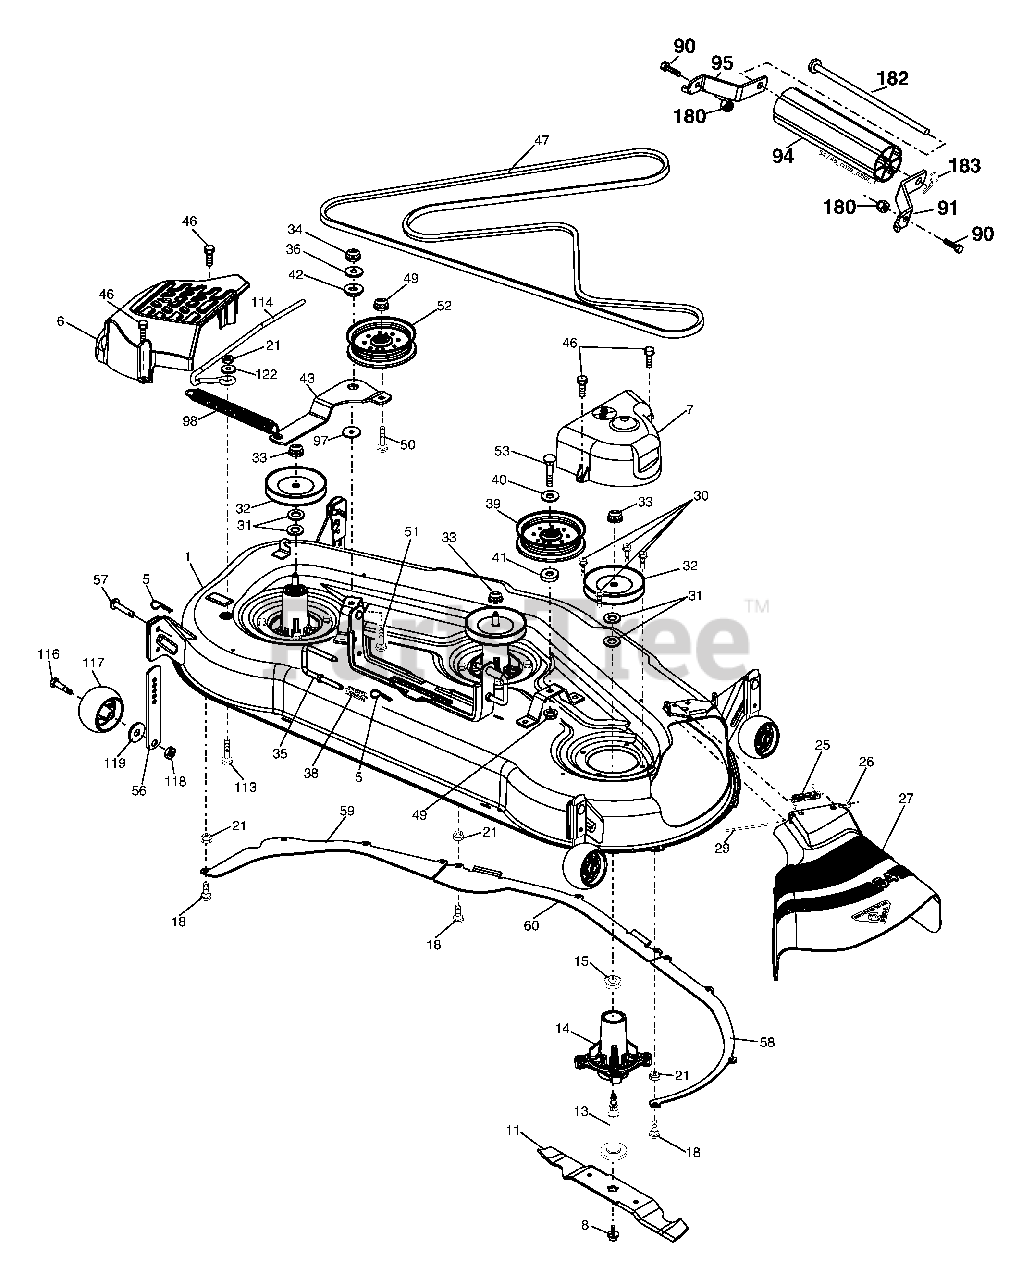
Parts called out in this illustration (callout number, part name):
1	Deck Weldment Mower
5	Retainer Spring
6	Cover Mandrel LH
7	Cover Mandrel RH
8	Bolt 7/16 Asm. Blade
11	Blade, Standard
13	Shaft Asm. w/Lower Bearing
14	Housing, Mandrel
15	Bearing, Ball, Mandrel
17	Bolt, Carriage 5/16-18 x 5/8
21	Nut, Crownlock 5/16-18 unc
25	Spring, Torsion
26	Nut, Push
27	Deflector Shield
29	Rod, Hinge
30	Screw, Thdroll Washer Head
31	Washer, Spacer Mower Vented
32	Pulley, Mandrel
33	Nut, Flg. Top Lock Cntr. 9/16
34	Nut
35	Pin Suspension Rear
36	Washer 13/32 x 13/16 x 16 Ga.
38	Spring Compression
39	Pulley, Idler, Stationary
40	Washer 13/32 x 13/16 x 12 Ga
41	Washer 13/32 x 1-3/8 x 3 Ga.
42	Spacer, Retainer
43	Arm, Idler
46	Screw, Thdroll. 1/4-20 x 5/8
47	V-Belt, Mower
49	Nut, Lock Flg. 3/8-16 unc
50	Bolt, Carr. 3/8-16 x 2
51	Bolt
52	Pulley Idler Clutching
53	Bolt Fin Hex 3/8-16 UNC x 2-1/4
56	Bar Pnt Adj.
57	Pin Head Rivet
58	Baffle Right
59	Baffle Left
60	Baffle Center
90	Bolt Hex HD 5/16-18 UNC x 1
91	Bracket Nose Roller RH
94	Roller Nose
95	Bracket Noseroller LH
97	Washer 13/32 x 2 x 10 Ga.
98	Spring Clutch Drive
113	Bolt Rdhd Sqnk 5/16-18 x 3/4
114	Rod Tension Relief
116	Bolt, Shoulder
117	Gauge Wheel
118	Nut, Centerlock 3/8-16 unc
119	Washer 3/8 x 7/8 x 14 Ga.
122	Bushing Tension Relief
180	Nut Lock HX w/Ins 5/16-18 UNC
182	Rod Roller Nose
183	Retainer Spring
